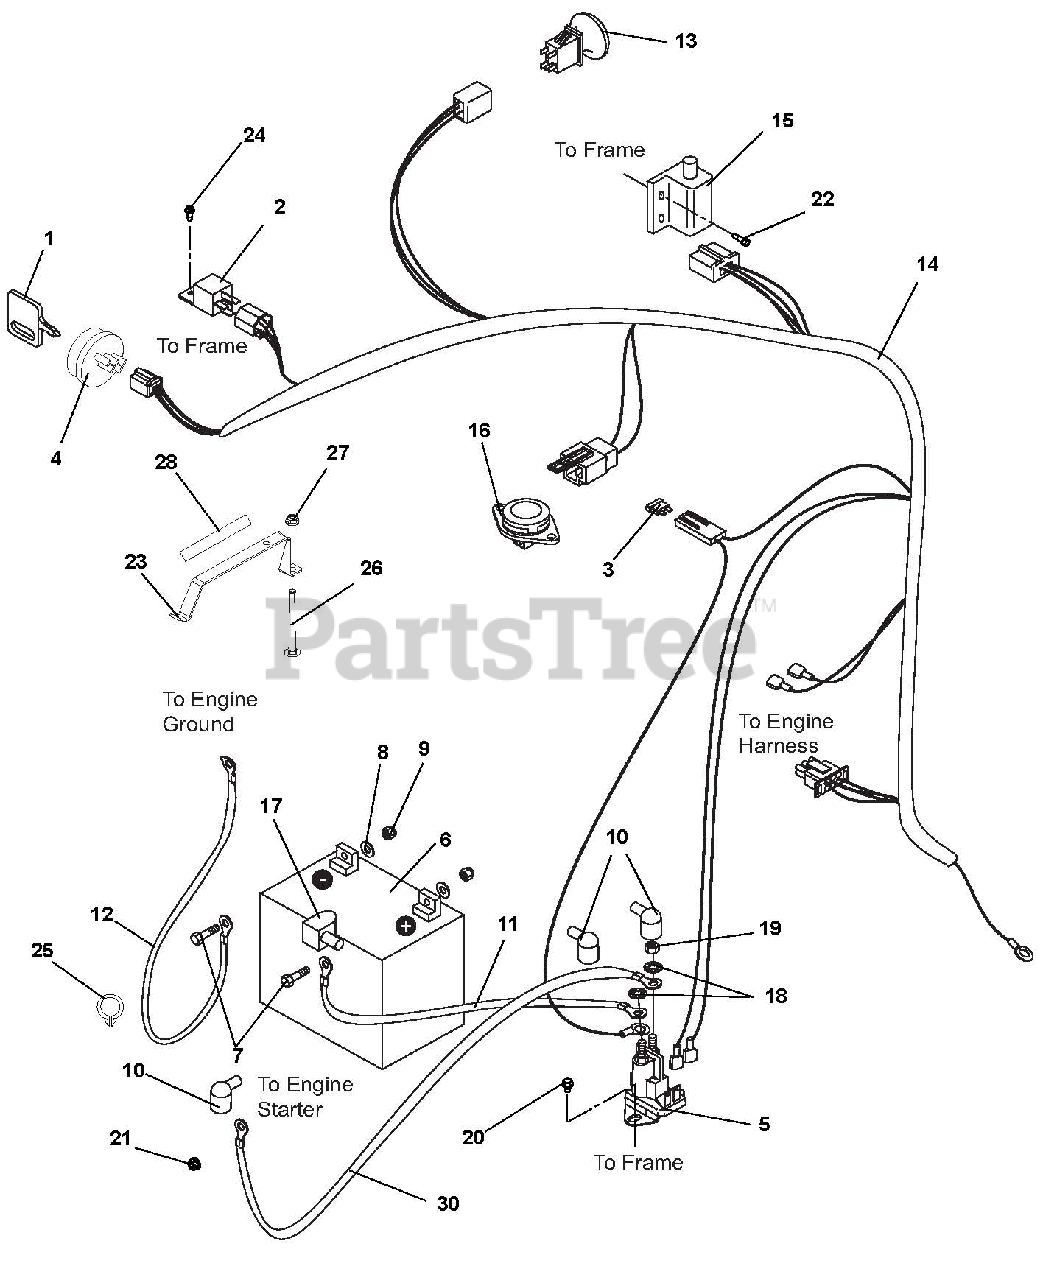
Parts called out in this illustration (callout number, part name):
1	KEY, IGNITION
2	RELAY
3	FUSE-25 AMP ATC TYPE
4	KEYSWITCH-IGNITION 3 POS
5	SOLENOID, STARTER (SEALED)
6	BATTERY, 12V 12A-190CCA
7	BLT, HEX .25-20X.75 G5 ZCC
8	WSHR,FLT .281X.625X.065 ZCC
9	NUT-KEPS .250-20 ZCC
10	BOOT, EYELET TERMINAL
11	CABLE,POS W/2 1/4 RING 15.0 LG
12	CABLE, NEGATIVE 26" 6 GA.
13	SWITCH, CLUTCH (YELLOW)
14	HARNESS, ZOOM STIGA/CE
15	SWITCH- DOUBLE POLE N.O./N.O.
16	SWITCH- SEAT
17	INSULATOR
18	WSHR,LK-EXT.262X.502X.026 ZCC
19	NUT-STD M6-1.0 ZCC
20	SCR,TAP .25-20X.375 HWH TR ZCC
21	NUT-LK-TOP-FLG .250-20 GF ZCC
22	SCR- 12-14X.75 HX W/HD TEK ZC
23	HOLDDOWN, BATTERY, U1&190CCA
24	SCR,TAP #10-24X.50 HWH TR ZCC
25	WIRE CLIP
26	BLT, RHSN .25-20X4.50 G5 ZCC
27	NUT,NYL-FLG .25-20 GF ZCC
28	DECAL, U1 BATTERY REPLACEMENT
29	CABLE TIE LG 5-1/2
30	CABLE,POS W/(2)1/4 RING 21.5LG
